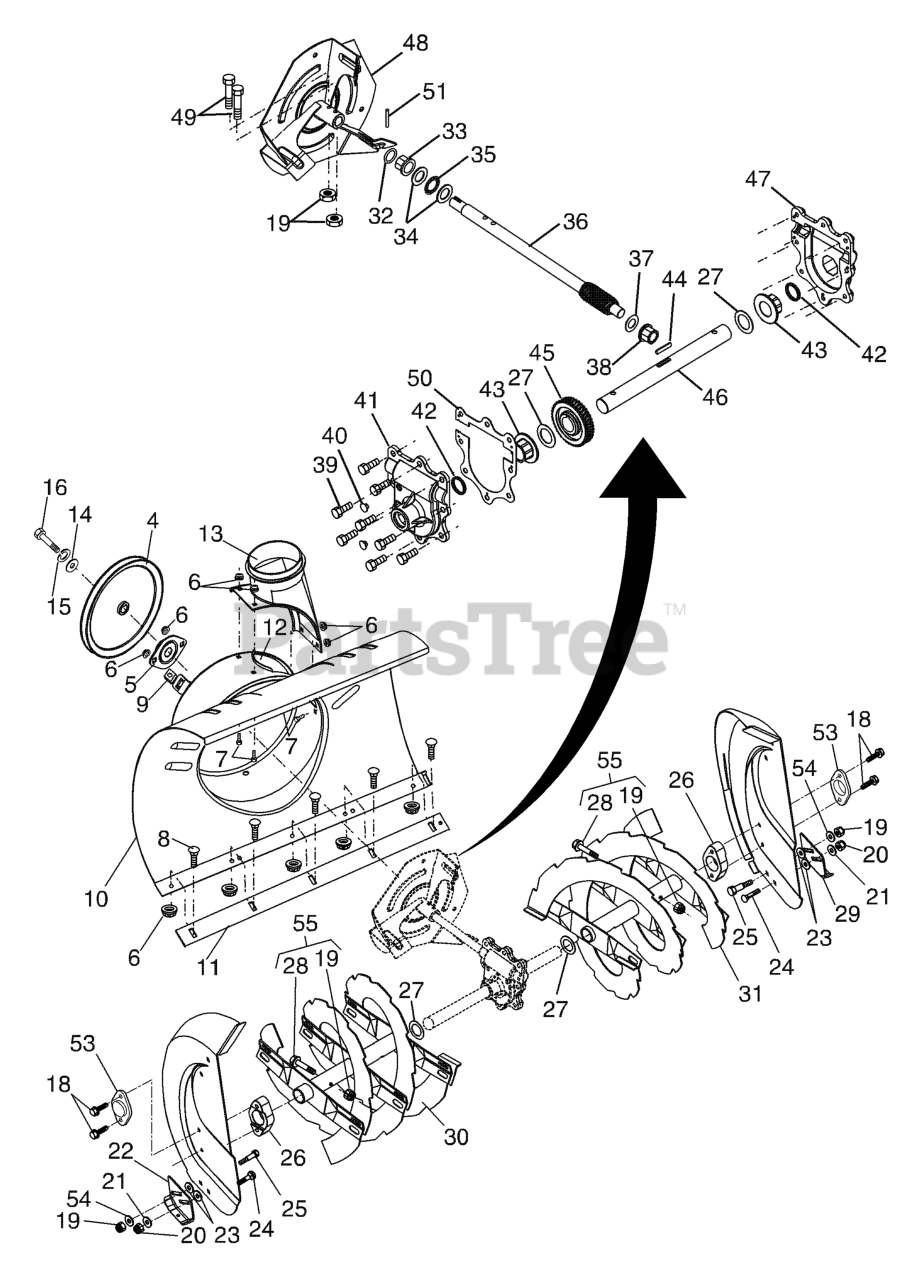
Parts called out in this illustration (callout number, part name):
4	PULLEY, IMPELLER
5	BEARING FLANGE
6	NUT.FLANGE.5/16
7	BOLT.CARRIAGE.5/16-18X
8	BOLT
9	NUT, CAGE 3/8-16
10	AUGER HOUSING WELDMENT
11	BAR, SCRAPER 27"
12	BRACKET, CORNER DISCHARGE
13	BASE DISCHARGE CHUTE
14	WASHER, FLAT
15	WASHER.LOCK.HVY.HLCL.SPR.5/16
16	Screw, Hex Head 5/16-18 x 3/4
18	SCREW, HEX HD 5/16X1
19	LOCKNUT.NYLOC.1/4-20
20	NUT.71038.31-18.HEX.NYLOCK
21	WASHER.20X8.5
22	SKID PLATE RH
23	WASHER, NYLON FRICTION
24	BOLT
25	SHOULDER BOLT
26	BEARING RETAINER, PLASTIC
27	WASHER TRUST 1"
28	BOLT.SHOULDER.SHEAR.1/4-20.
29	SKID PLATE LH
30	AUGER ASM 27" RH
31	AUGER ASM 27" LH
33	BUSHING FLANGE 3/4
34	WASHER, THRUST 3/4
35	BEARING TRUST 3/4 NTA-1220
36	SHAFT, IMPELLER
37	WASHER, THRUST 5/8
38	BUSHING.FLANGE.(.625X.75)
39	SELF-TAPPING SCREW 5/16-18X3/4
40	PLUG.AUGER.GEAR.BOX.SNOW
41	HOUSING.GEARBOX.RH.SNOW
43	BUSHING FLANGE 1"
44	KEY, SQUARE 1/4 X .875
45	WORM GEAR
46	SHAFT, AUGER
47	LH GEARBOX HOUSING
48	IMPELLER ASSY
49	SCREW.HEX.HD1/4-20X
50	GASKET.AUGER.GEARBOX
51	PIN, ROLL 3/16 X 1-1/8
53	BEARING.BALL.AUGER.SHAFT
54	WASHER
55	KIT, BOLT, SHEAR
